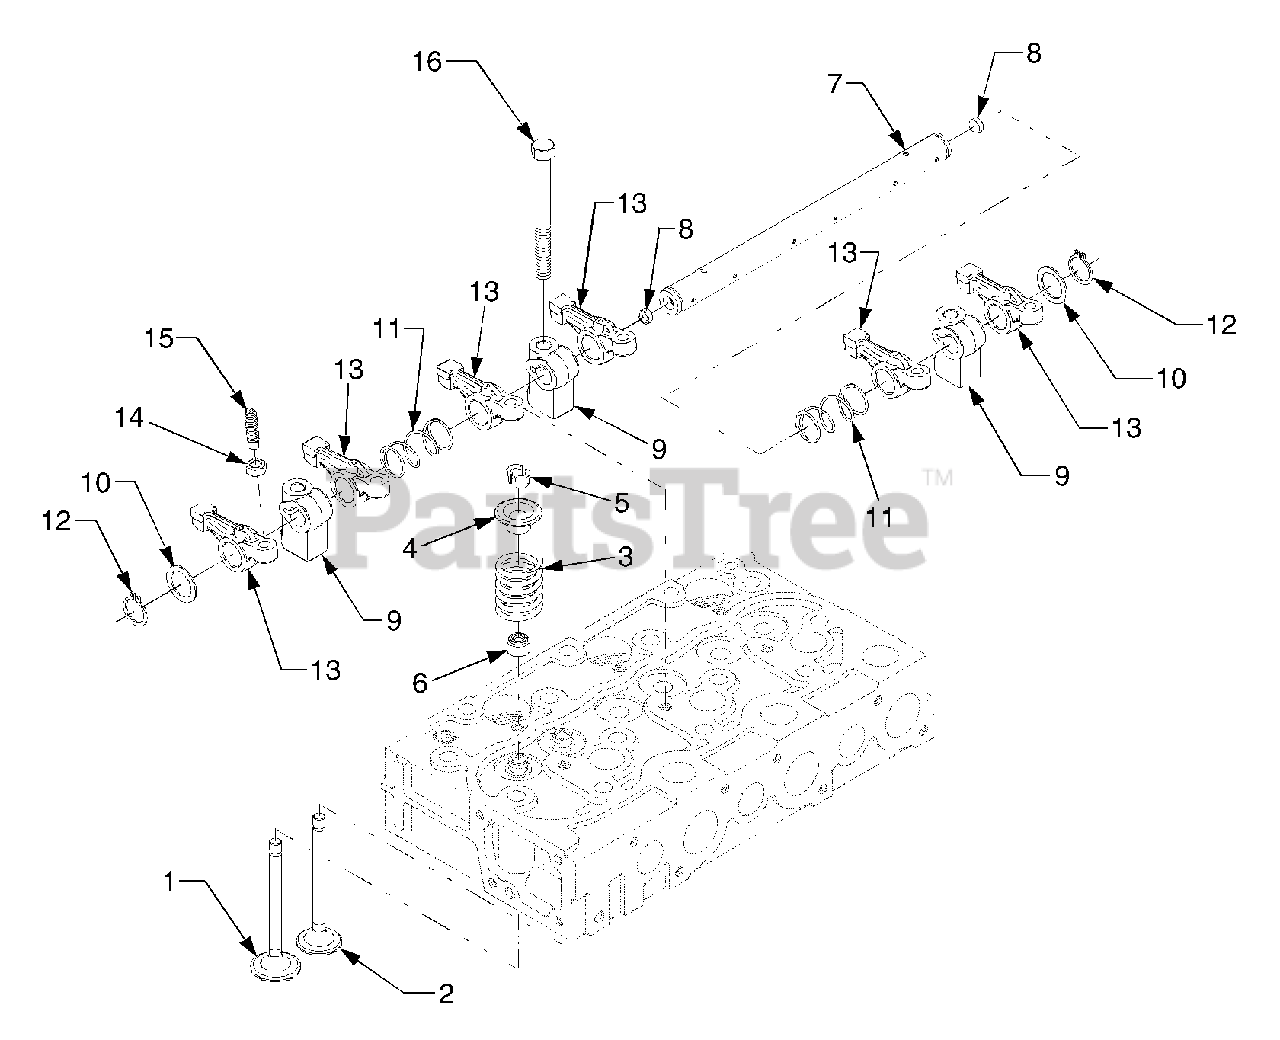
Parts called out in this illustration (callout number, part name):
2	Valve, Outlet
3	Spring, Valve
4	Retainer, Valve Spring
5	Collet, Valve Spring
6	Seal, Valve Stem
7	Rocker Arm Shaft Ass'y
9	Bracket, Rocker Arm
10	Washer, Plain
11	Spring, Rocker Arm
14	Nut, Adjusting
15	Screw, Adjusting
16	Bolt, Rocker Arm
